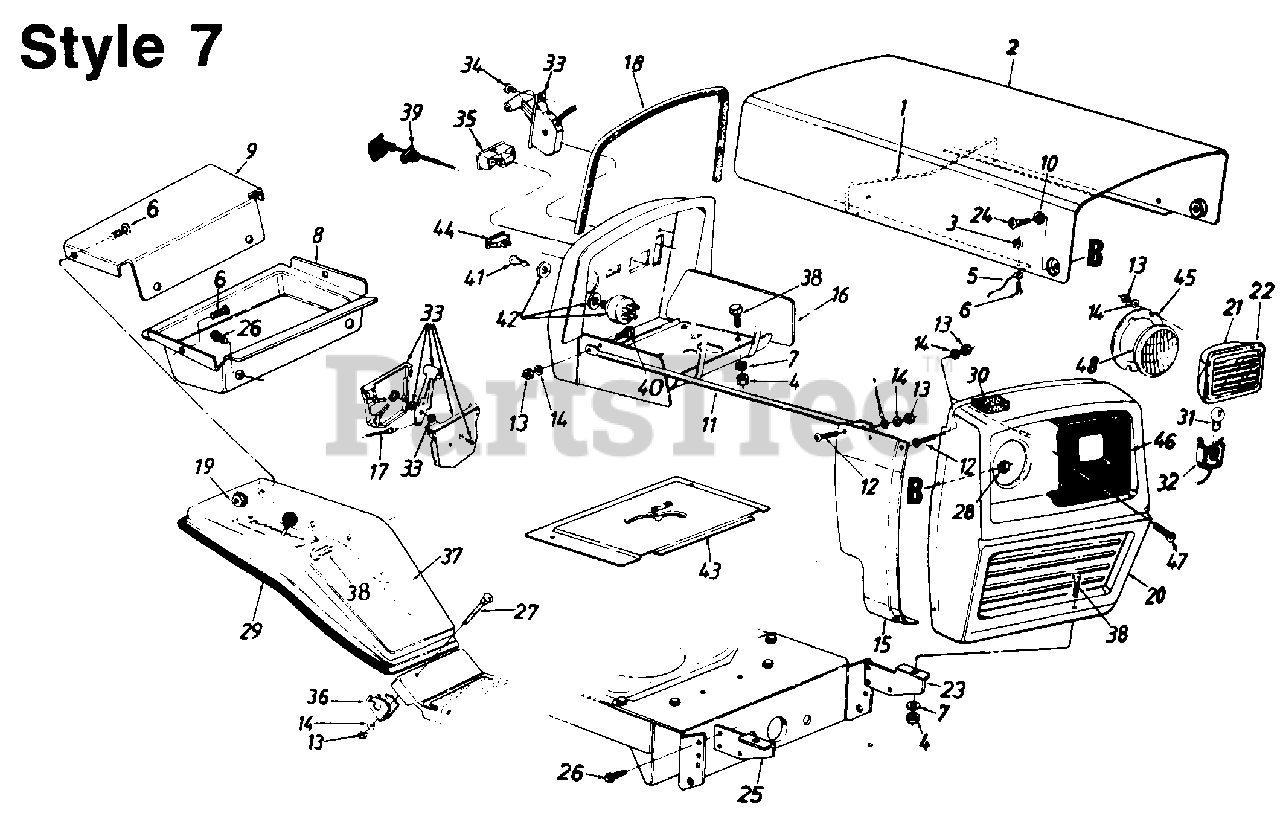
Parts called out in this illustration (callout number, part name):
1	Hood Spring
4	Hex Nut 5/16-18 Thd.
5	Hood Stop 7" Lg.
6	Truss Hd. Scr. #10-24 x 1/2"
7	L-Wash. 5/16" I.D.
8	Tool Tray
11	Grille Support Rod
12	Truss Hd. Scr. 1/4-20 x .75"
13	Hex Nut 1/4-20 Thd.
14	L-Wash. 1/4" I.D.
15	R.H.-Grille Side Panel
17	Throttle Control Wire-B&S
18	Molding Strip 31" Lg.
19	Hex Sems Nut #10-24 Thd.
22	Headlight Lens
23	Mounting Brkt.
24	Shld. Bolt .375" Dia. x .125"
27	Carriage Bolt 1/4-20 x 2.0" Lg.
28	L-Nut 1/4-28 Thd.
29	Trim Strip-57" Lg.
30	Foam Strip 3/8 x 1-1/8 x 11/2
31	Head Lamp
32	Twist Lock Lamp Socket
33	Throttle Box Ass'y.
34	Truss Mach. AB-Tap Scr. #10 x .5" Lg.
35	Ammeter
36	Fender Clamp
39	Choke Control 29" Lg.
40	Hex Bolt 1/4-20 x .62" Lg.
41	Ignition Key
42	Ignition Switch
43	Shift Cover
44	Light Switch
45	Headlight Retainer
46	Bezel
47	Oval C-Sunk Scr. 1/4-20 x 1.5"
48	Round Headlight
